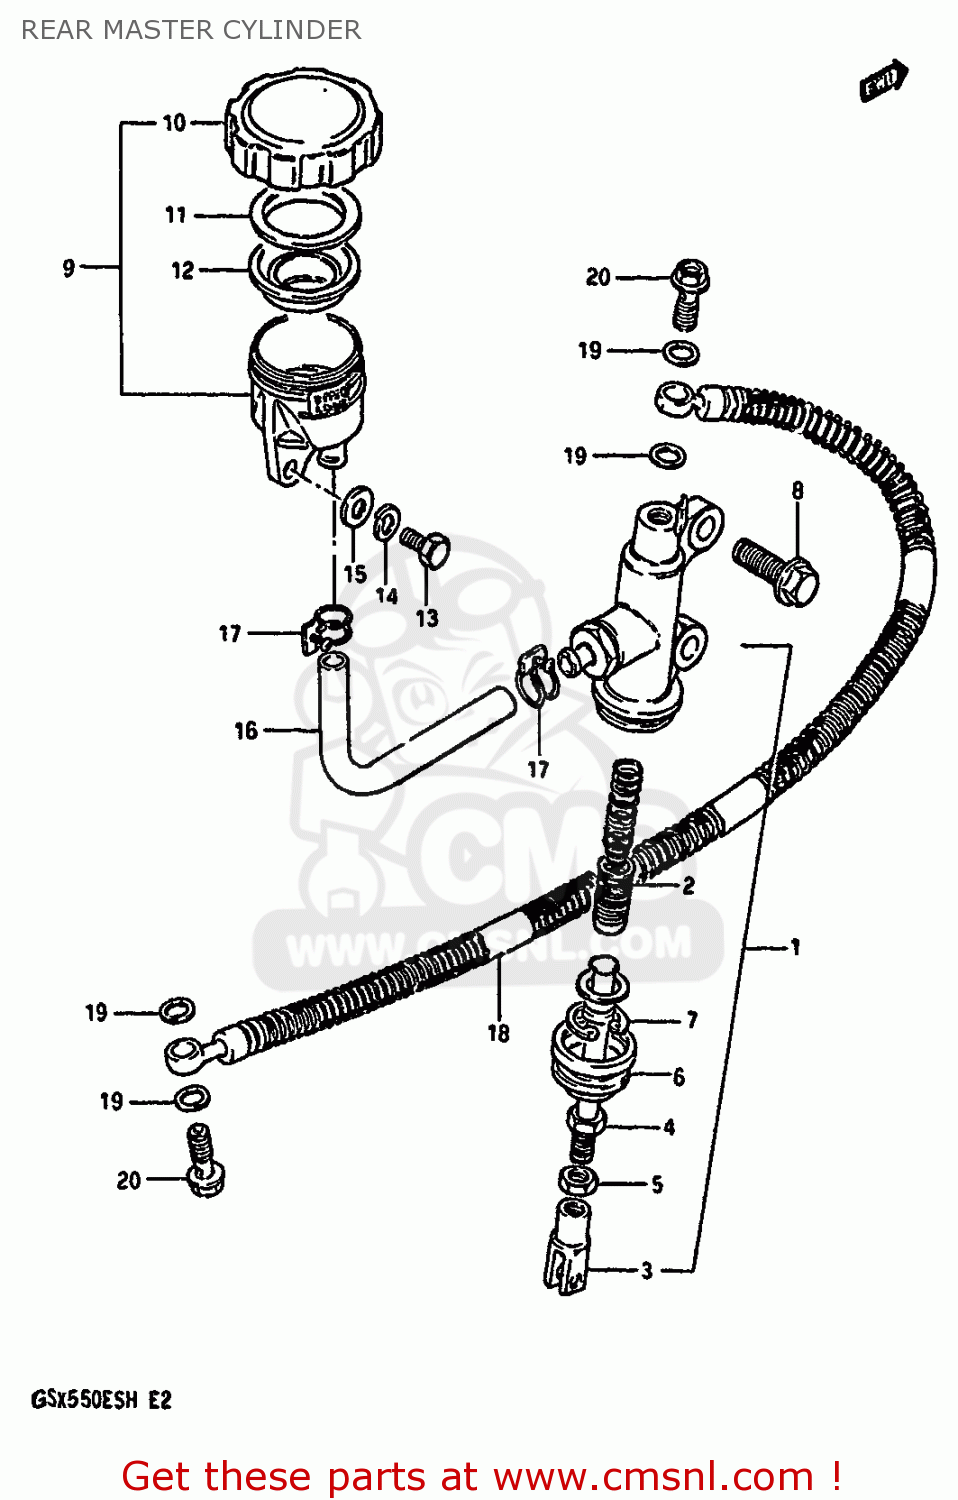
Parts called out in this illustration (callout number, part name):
1	CYLINDER ASSEMBLY,REAR MASTER
2	PISTON/CUP SET
3	YOKE
4	ROD,PUSH
5	NUT,MASTER CYLINDER
6	BOOT
7	CIRCLIP
8	BOLT
9	TANK ASSEMBLY,RESERVOIR
10	CAP
11	PLATE,DIAPHRAGM
12	DIAPHRAGM
13	BOLT
14	WASHER,LOCK
15	WASHER
16	HOSE,RESERVOIR TANK
17	CLAMP
18	HOSE,REAR BRAKE
19	WASHER(10X15X1.5)
20	BOLT UNION
